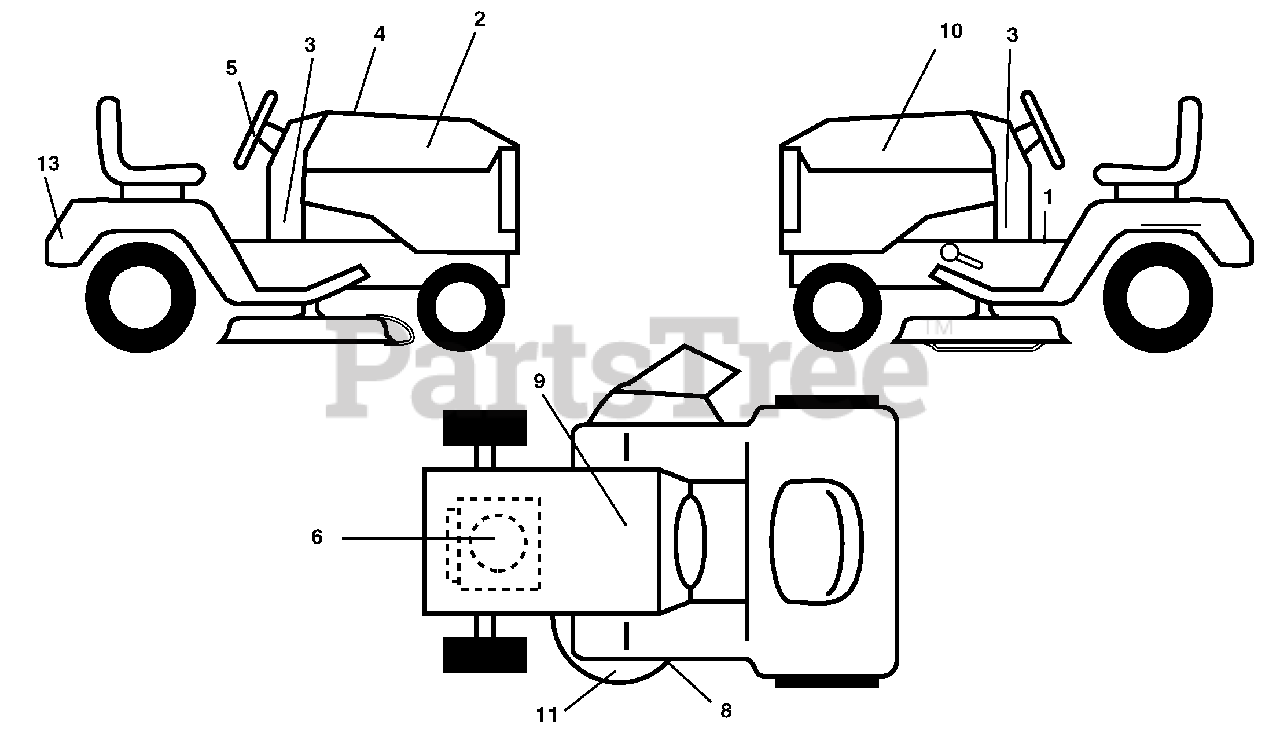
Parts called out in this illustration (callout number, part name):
1	Decal, Operator's
2	Decal, Hood RH
3	Decal, Dash Lower
4	Decal, Replacement
5	Decal, Strg Whl
6	Decal, Engine HP
8	Decal, Mower Sch.
9	Decal, Battery Dnge/Poi
10	Decal, Hood LH
11	Decal, Mower Caution
12	Decal, Fender
13	Decal, Bypass
13	Pad, Footrest, RH
13	Pad, Footrest, LH
13	Manual, Operator's E&SP
13	Manual, Parts
